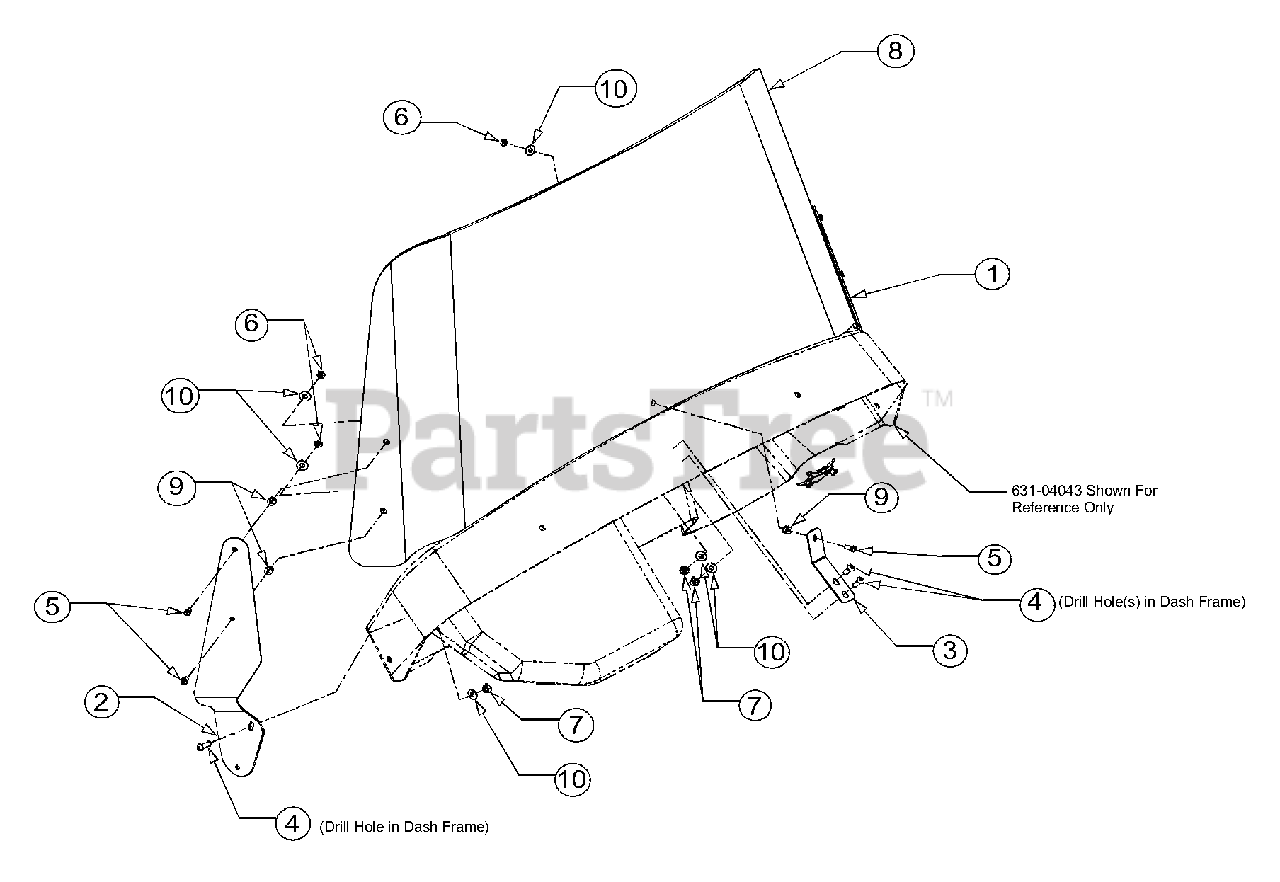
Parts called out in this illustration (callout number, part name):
1	Bracket, LH Windshield
2	Bracket, RH Windshield
3	Bracket, Windshield, Middle
4	Screw, Machine 1/4-20 x .75
5	Screw, #10-32
6	Nut, #10-32
7	Nut, Hex 1/4-20 GR 5
8	ACSRY, Windshield Plastic
9	Grommet
10	Washer, Flat .271x.630x.065
